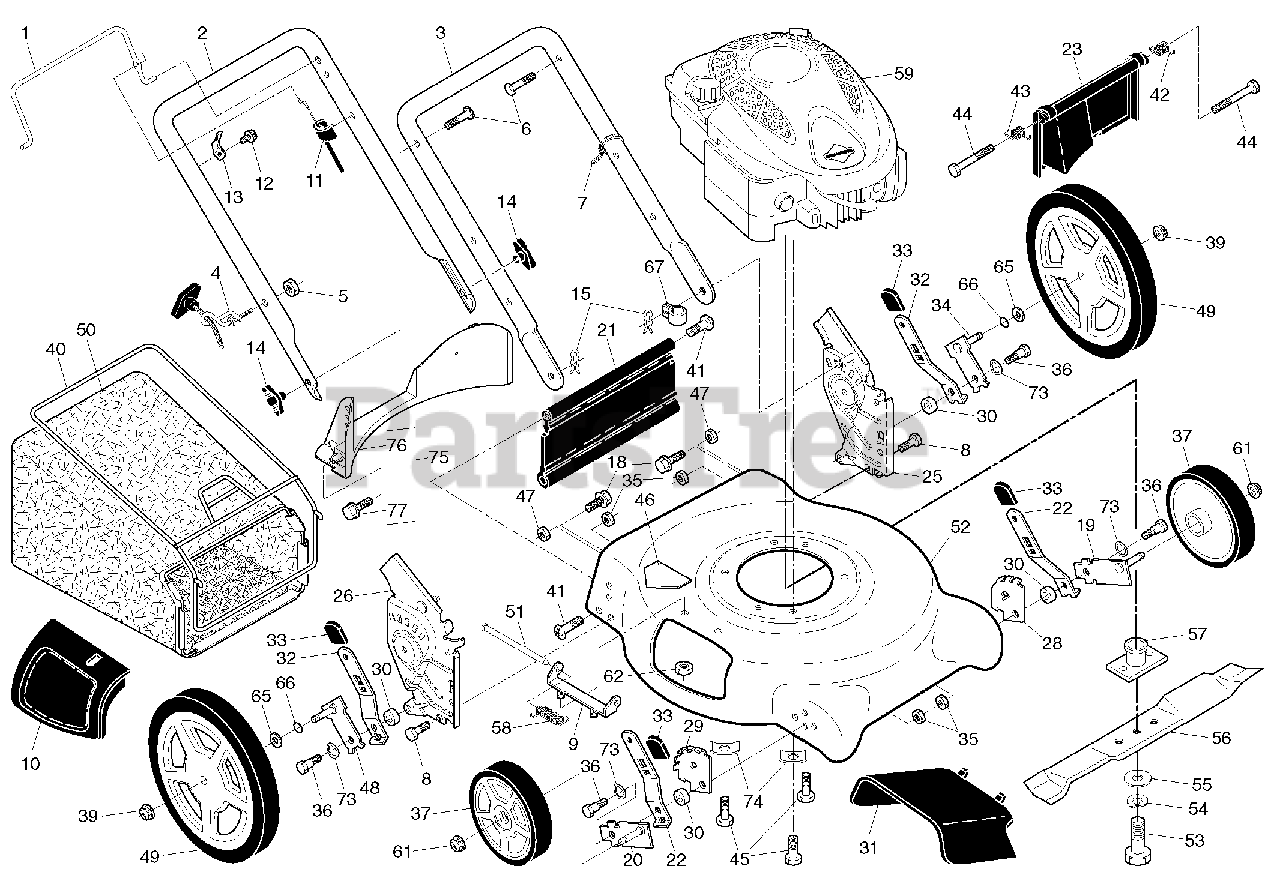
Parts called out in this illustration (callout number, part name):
1	Control Bar
2	Upper Handle
3	Lower Handle
4	Rope Guide
6	Handle Bolt
7	Wire Tie
8	Bolt, Hex Head 5/16-18 x 3/4
9	Hinge Bracket
10	Mulcher Door
11	Engine Zone Control Cable
12	Hex Washer Head Screw #10-24 x 1/2
13	Up-Stop Bracket
14	Handle Knob
15	Hairpin Cotter
18	Screw
19	Axle Arm Assembly, Front, LH
20	Axle Arm Assembly, Front, RH
21	Kit, Rear Skirt
22	Selector Spring, Front
23	Rear Door Assembly
25	Handle Bracket, LH
26	Handle Bracket, RH
28	Wheel Adjusting Bracket, Front, LH
29	Wheel Adjusting Bracket, Front, RH
30	Spacer
31	Discharge Deflector
32	Selector Spring, Rear
33	Selector Knob
34	Axle Arm Assembly, Rear, LH
35	Locknut, Hex 5/16-18
36	Shoulder Bolt 5/16-18
37	Wheel & Tire Assembly, Front 7 x 1-3/4
39	Nut, Hex
40	Frame, Grassbag
41	Screw, Hinge
42	Spring, LH
43	Spring, RH
44	Bolt, Rear Door
45	Hex Head Thread Rolling Screw 3/8-16 x 1
46	Danger Decal
47	Nut, Hex
48	Axle Arm Assembly, Rear, RH
49	Wheel & Tire Assembly, Rear 12 x 1-3/4
50	Grassbag
51	Hinge Rod
52	Kit, Housing
53	Screw, Hex Head, Grade 8 3/8-24 x 1-3/8
54	Helical Lockwasher
55	Hardened Washer
56	21" Blade
57	Blade Adapter
58	Hinge Spring
61	Flanged Locknut
62	Nut, Hex
65	Washer, Flat
66	O-Ring
67	Clip, Cable
73	Washer, Curved, Cylindrical
74	Washer, Special, Engine
75	Kit, Rear Baffle
76	Baffle, Rear
77	Screw, Rear Baffle
